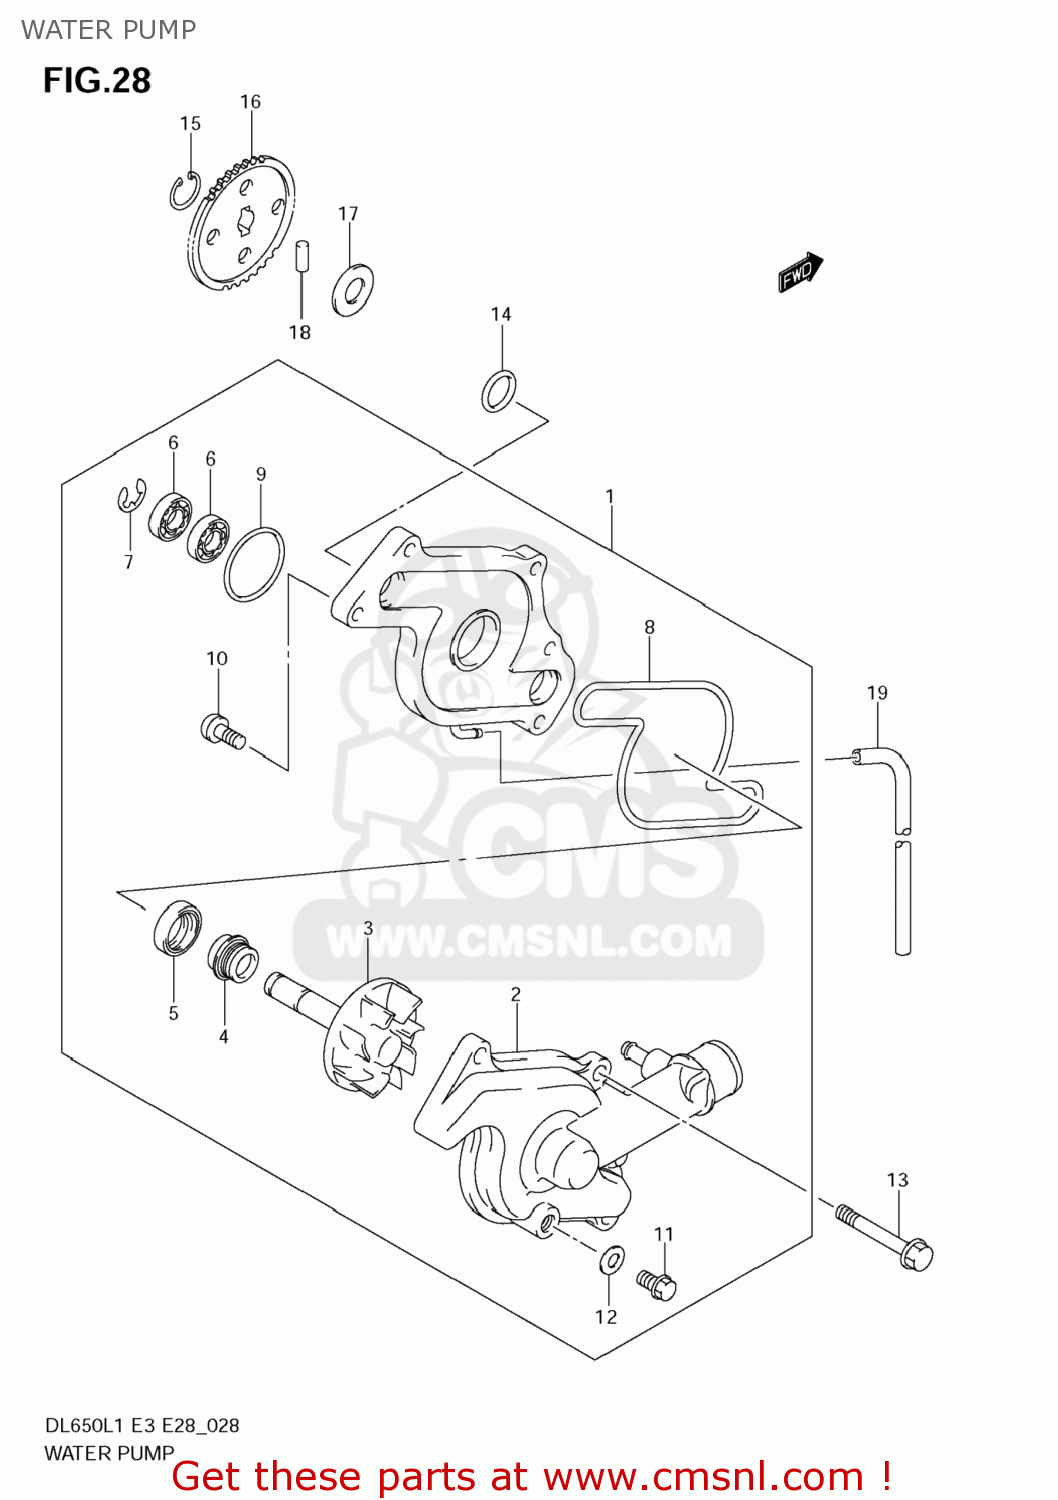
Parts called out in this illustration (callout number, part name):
1	PUMP ASSY,WATER
2	CASE,WATER PUMP
3	IMPELLER/SHAFT
4	SEAL,MECHANICAL
5	SEAL,OIL(10X21X5)
6	BEARING(10X26X8)
7	E RING
8	O RING
9	O RING,WATER PUMP HOLDER
10	SCREW
11	BOLT,DRAIN
12	GASKET(8.2X14X1) (NAS)
13	BOLT(6X55)
14	O RING(D:2.4,ID:21.8)
15	CIRCLIP
16	GEAR,WATER PUMP DRIVEN
17	SHIM(10X18X0.5)
18	ROLLER(4X13.8)
19	HOSE(3.5X6.5X600)
